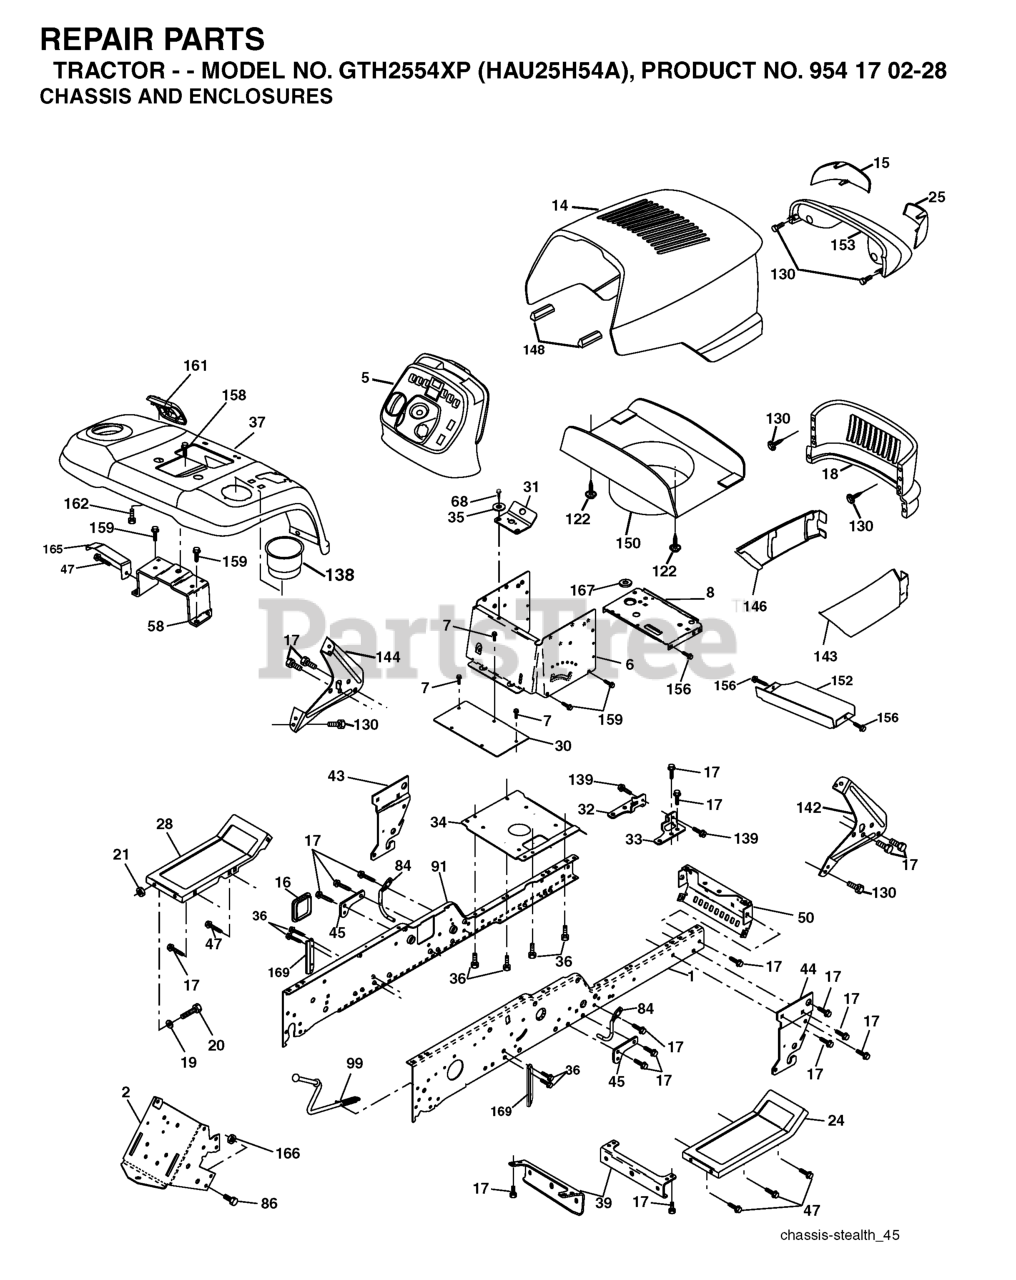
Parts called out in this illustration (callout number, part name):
1	KIT.RAIL.CHASS.RH.GT
2	DRAWBAR, GT
5	DASH
6	DASH VGT, LOWER
7	SCREW
8	SUPPORT, BATTERY
14	HOOD
15	LENS LH
16	COVER ACCESS
17	SCREW, 3/8-16X3/4
18	GRILLE.STEALTH P/L.YTGT.GREY
19	WASHER
21	NUT
24	FOOTREST PNT RH
25	LENS RH
28	FOOTREST PNT LH
30	SADDLE.HYDRO.95
31	BRACKET SUPT 1-PC VGT STEERING
34	PLATE ASM ENG CHASSIS
35	WASHER
36	SCREW 5/16"
37	FENDER, PNT
39	BRACKET AXLE, FRONT
43	FRONT SUSPENSION BRKT LH
44	FRONT SUSPENSION BRKT RH
45	BRACKET ARM SUSPENSION
50	BRACKET, CHASSIS FRONT
58	BRACKET ASM., FENDER
68	Screw 5/16-18 x 1/2 Hex, Self Tapping 5/16-18 x 1/2
84	UPSTOP 54"
91	KIT.RAIL.CHASS.LH.GT
99	ROD ASM, BYPASS
122	SCREW.HEX.WS.HD.8-18 X 7/8
130	SCREW
138	CUPHOLDER
139	BOLT, SHOULDER 5/16-18
142	BRACKET DASH STEALTH(R)
143	SKIRT GRILLE RH
144	BRACKET DASH STEALTH LH
146	SKIRT GRILLE LH
148	EXTRUSION BUMPER (3 2) (2 2)
150	DUCT.HEAT.HOOD.STEALTH.GT
152	BROWNING SHIELD
153	LIGHTBOX.ASM.STV.DL.INC.HUSQ
156	SCREW 5/16"
158	SCREW 3/8-16X1/2
159	SCREW, 3/8-16X3/4
161	CONSOL.FUEL.WINDOW.BLACK
162	SCREW.HI-LO.CONSOLE
165	BRACKET SUPPORT TANK
166	Nut, Crownlock Hex 7/16-14 unc
167	BUSHING SNAP
168	SCREW, 3/8-16X3/4
169	BRACKET CHASSIS SWAY
170	Bolt Shoulder
